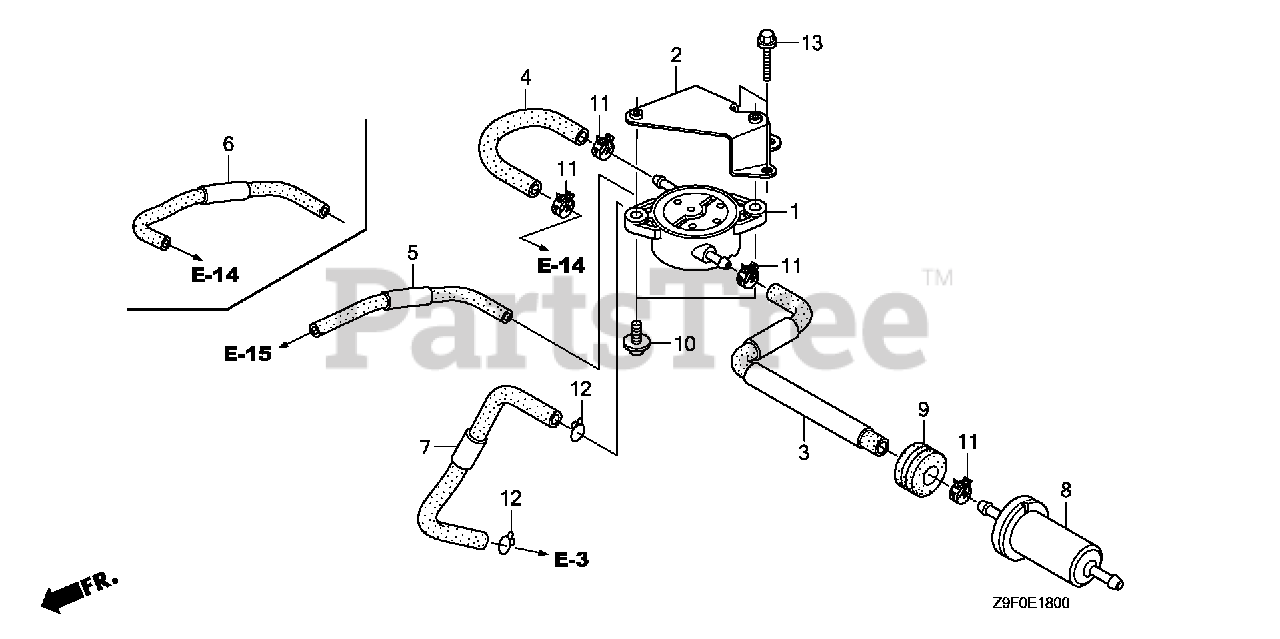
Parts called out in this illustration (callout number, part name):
1	PUMP ASSY., FUEL (MSDS)
2	STAY, FUEL PUMP
3	TUBE A, FUEL (FKM)
4	TUBE B, FUEL (FKM)
5	TUBE, PURGE
7	TUBE, DIAPHRAGM
8	FILTER, FUEL
9	RUBBER, RR. FENDER
10	SCREW, TRUSS (6X12)
11	CLAMP, TUBE (D10)
12	CLIP, TUBE (C11)
13	BOLT, FLANGE (6X14)
